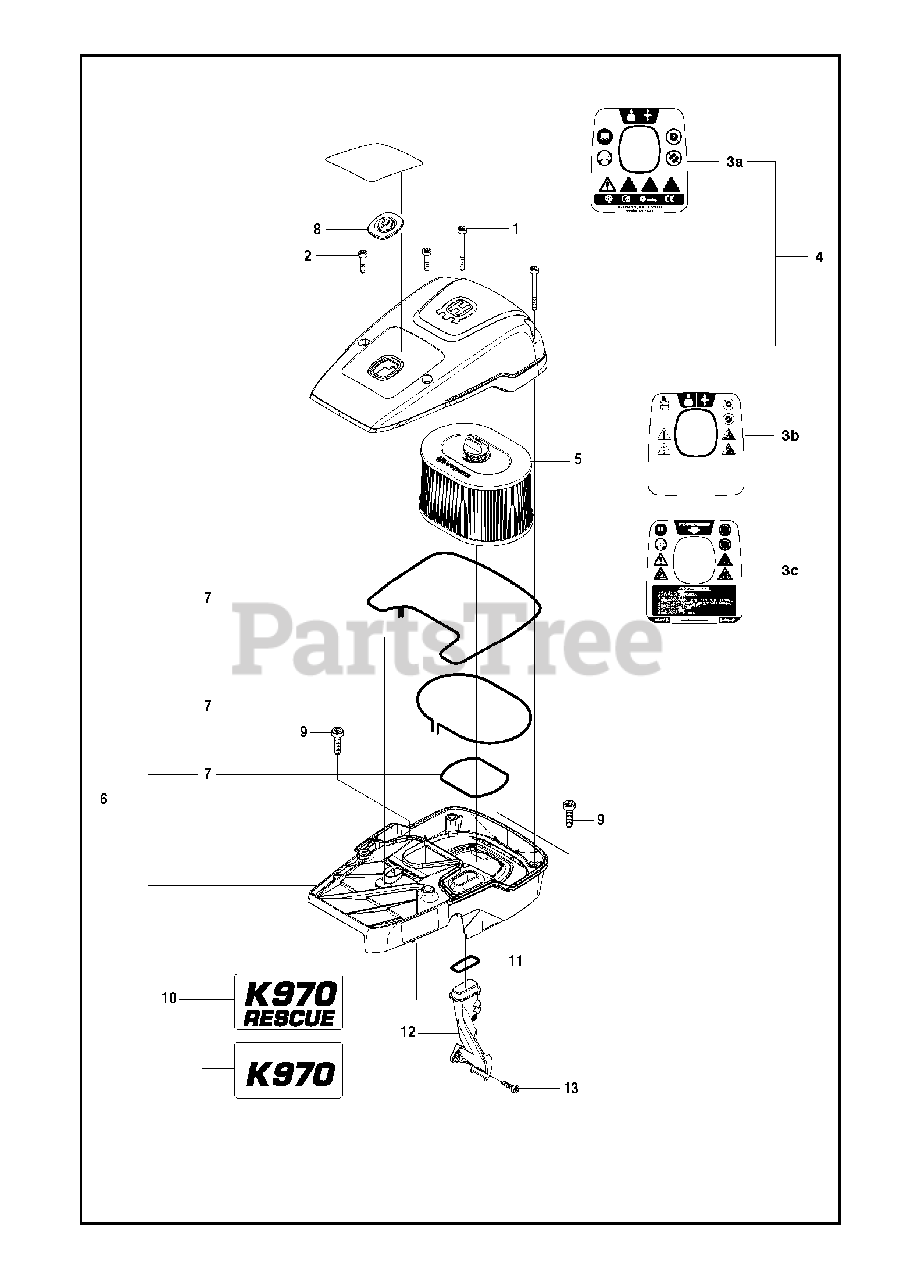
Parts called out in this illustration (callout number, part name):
1	SCREW ITXSCM
2	SCREW ITXSCM
4	FILTER COVER ASSY
5	AIR FILTER
6	CYLINDER COVER ASSY
9	SCREW ITXSCM
13	SCREW ITXSCM
